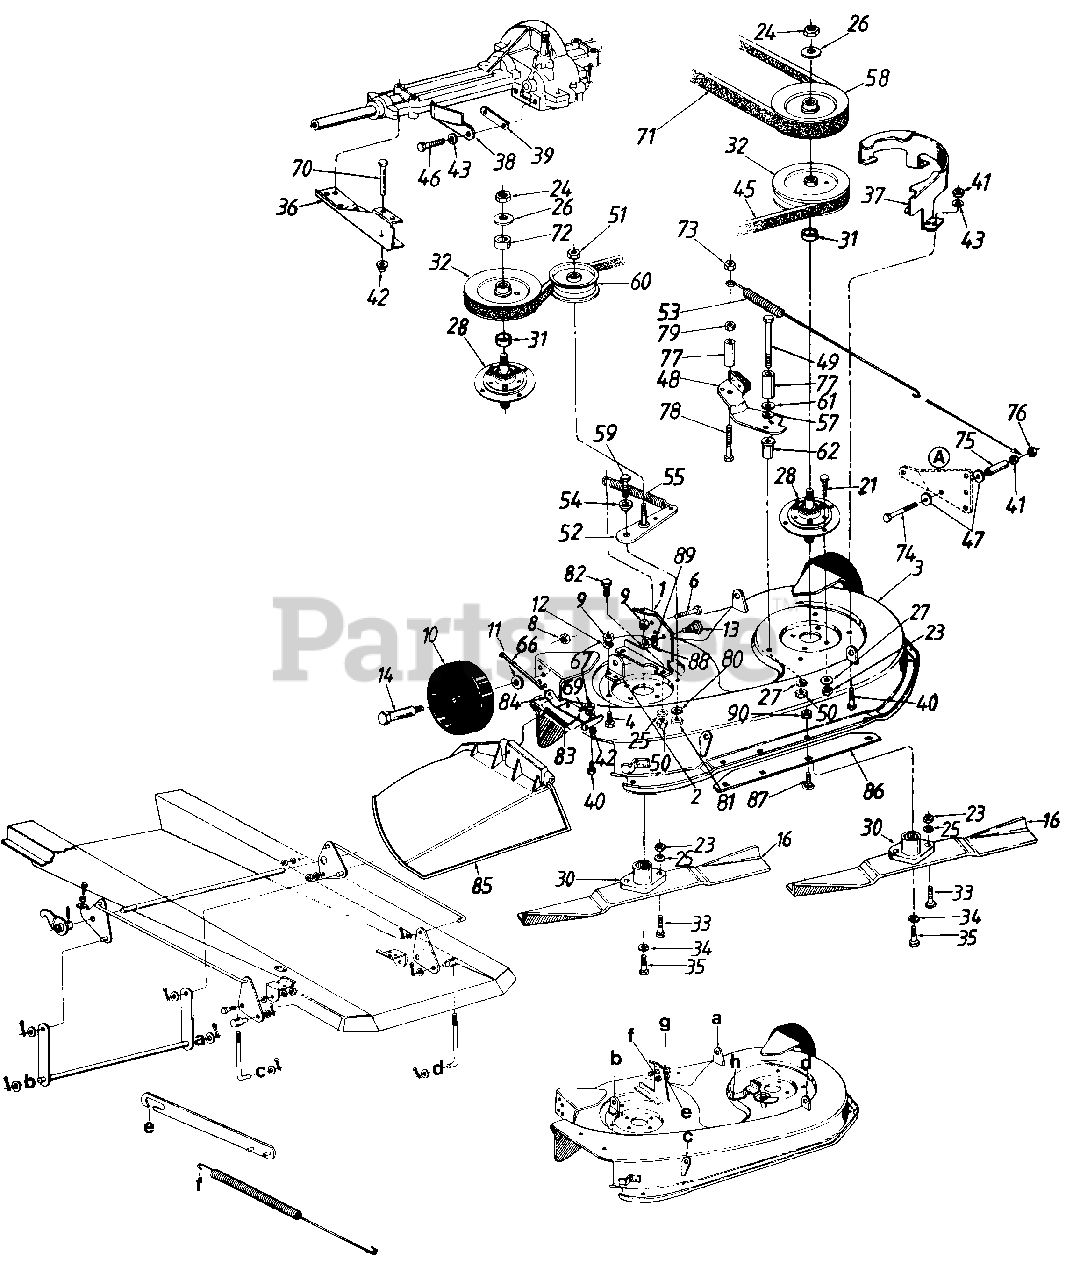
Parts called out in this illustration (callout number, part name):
1	Deck Disengagement Brkt.
2	Rear Deck Brkt.-R.H.
3	38" Deck Ass'y.
4	Hex Bolt 1/4-20 x .62" Lg.
6	Hex Wash. Hd. Scr. 1/4-20 x 1.5" Lg.
8	Hex L-Nut 3/8-16 Thd.
9	Hex Nut 1/4-20 Thd.
10	Deck Wheel
11	Bell-Wash. .380 I.D. x .88
12	L-Wash. 1/4 I.D.
13	Shld. Bolt .500 Dia. x .336" Lg.
14	Shld. Bolt .498 Dia. x 1.53" Lg.
16	High-Lift Blade
21	Hex Bolt 5/16-24 x .75" Lg.
23	Hex Nut 5/16-24 Thd.
24	Hex Jam Nut 5/8-18 Thd.
25	L-Wash. 5/16" I.D.*
26	L-Wash. 5/8" I.D.
27	Bell-Wash. .345 I.D. x .88
28	Blade Spindle Ass'y. Comp.
30	Blade Adapter
32	5" Dia. Pulley (1" Hub)
33	Hex Bolt 5/16-24 x 1.0" Lg. (Special)
34	L-Wash. 3/8" I.D. H.D.
35	Hex Bolt 3/8-24 x 1.0" Lg.
39	Belt Guard Spacer
40	Hex Bolt 1/4-20 x .62" Lg.
41	Hex Nut 1/4-20 Thd.
42	Cap Speed Nut 1/4" Rod
43	L-Wash. 1/4" l.D.
45	V-Belt
46	Hex Bolt 1/4-20 x .85" Lg.
47	Fl-Wash. 1/4" I.D.
48	Deck Brake Brkt. Ass'y.
49	Hex Bolt 5/16-18 X 3.251' Lg.
50	Hex Nut 5/16-18 Thd.
51	Hex L-Nut 3/8-24 Thd.
52	Idler Brkt. Ass'y.
53	Extension Spring 17.75" Lg.
54	Shoulder Spacer .625" I.D.
55	Extension Spring 7-3/4" Lg.
57	Wave Washer .53" l.D. x .78 O.D.
58	5" Dia. Pulley (3/4" Hub)
59	Hex Bolt 3/8-16 X 1" Lg.
60	Flat Idler Pulley
61	Shld. Spacer .51" I.D. x .27n Lg.
62	Spacer .31" I.D. x 1.46" Lg.
66	Hinge Pin 1/4" Dia. x 5.75" Lg.
67	Hex Nut 1/4-20 Thd.
69	Bell-Wash. 1/4n l.D.
70	Pin .25" Dia. x 2.5" Lg.
71	V-Belt
73	Hex L-Nut l/4-28 Thd.
74	Hex Bolt 1/4-20 x 2.5 Lg.*
75	Spacer 1/4n l.D. x 3/8n O.D.
76	Hex L-Nut 1/4-20 Thd.
77	Spacer 5/16 I.D. x 1/2" O.D.
78	Hex Bolt 1/4-28 x 1.75n Lg.
79	Hex Nut 1/4-28 Thd.
80	L-Wash. 3/8" I.D.
81	Hex Nut 3/8-16 Thd.
82	Hex Bolt 5/16-18 x .75" Lg.
83	Torsion Spring
84	Hinge Mtg. Brkt.
85	Chute Ass'y. Comp.
88	Hex Nut 3/8-16 Thd.
89	L-Wash. 3/8" l.D.
90	Hex Sems Nut 1/4-20 Thd.
